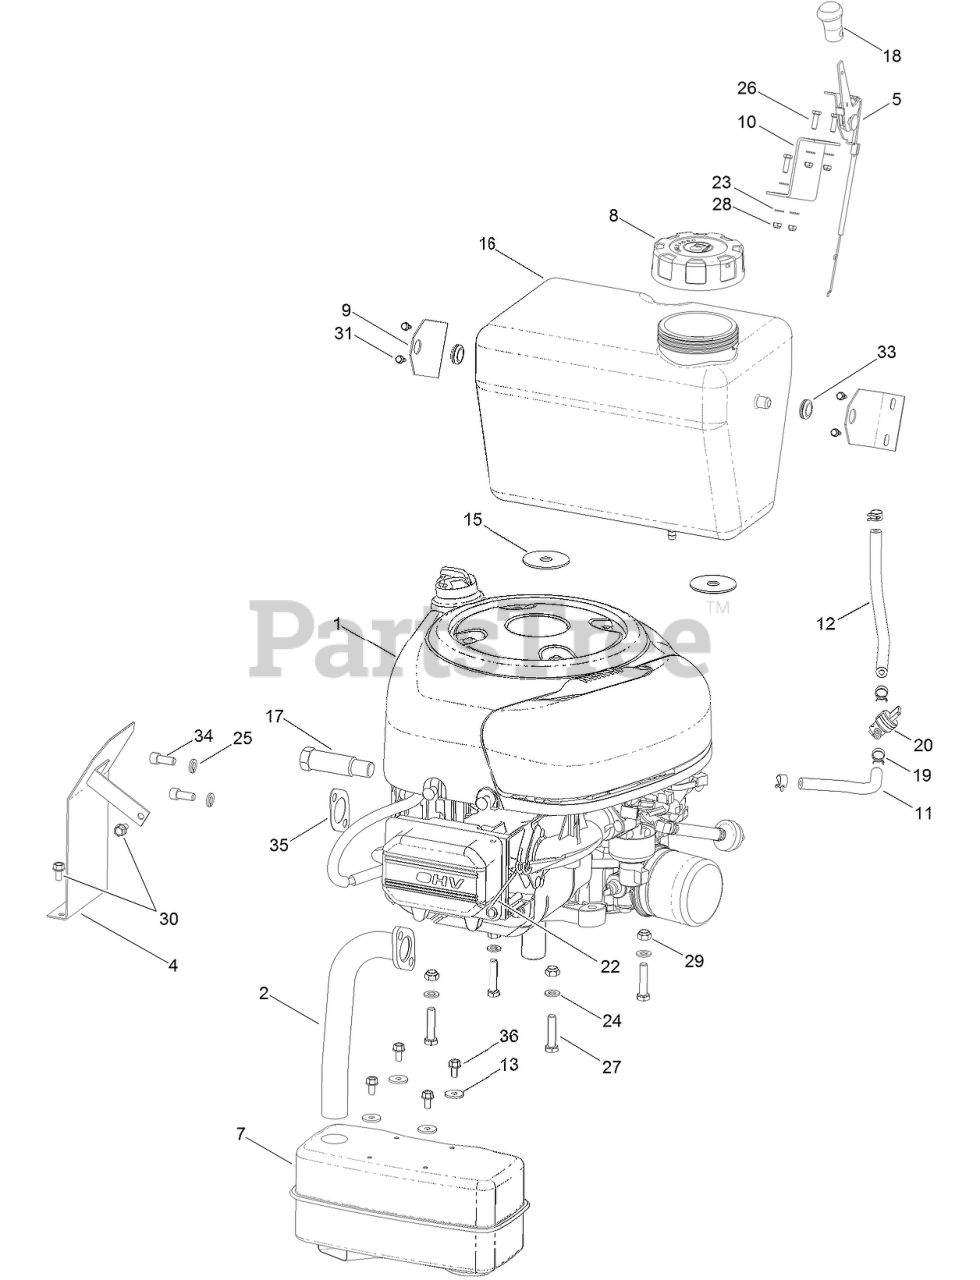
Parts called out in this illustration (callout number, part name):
2	TUBE-EXHAUST
4	COVER-EXHAUST
5	CABLE-THROTTLE/CHOKE
7	MUFFLER
8	CAP-FUEL
9	BRACKET-FUEL, TANK
10	HOLDER
11	LINE-FUEL
12	LINE-FUEL
13	WASHER-FLAT
15	WASHER-RUBBER
16	TANK-FUEL
17	COUPLER-DRAIN, OIL
18	KNOB-THROTTLE/CHOKE
19	CLAMP-LINE, FUEL
20	VALVE-TANK, FUEL
22	HOLDER-HARNESS, WIRING
23	WASHER
24	WASHER-PLAIN
25	WASHER-SPRING
27	SCREW-HH
28	NUT-LOCK
29	NUT-LOCK, NI
30	SCREW-HH
31	SCREW-TAP
33	BUSHING
34	SCREW-HH
35	GASKET
36	SCREW-HHTF
